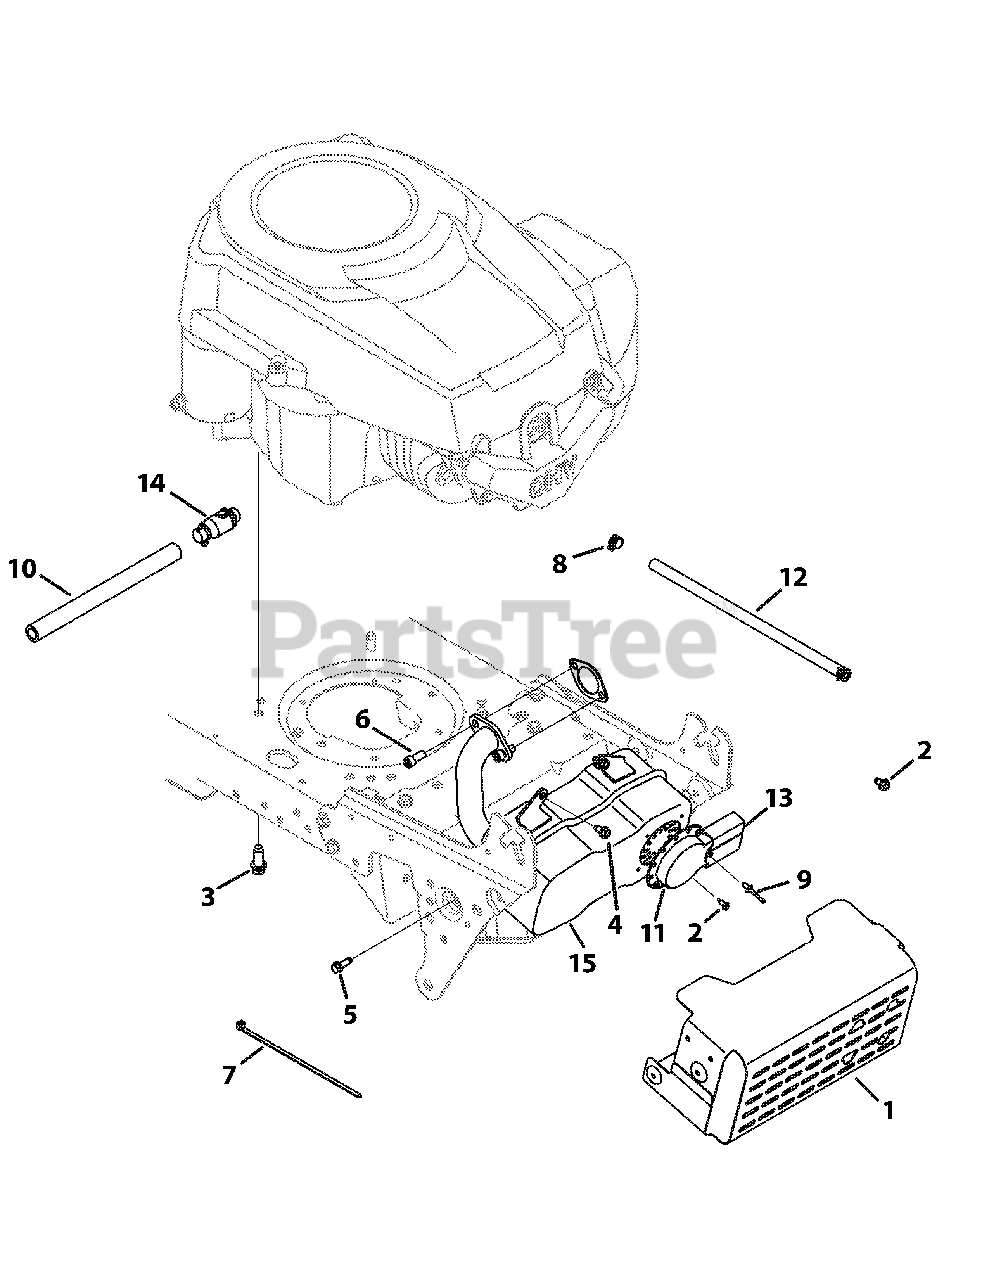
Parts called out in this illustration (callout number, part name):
1	Muffler Shield Assembly with Weld
2	Screw, 8-18 x .500
3	Screw, 3/8-16 x 1.0
4	Screw, 1/4-20 x .500
5	Screw, 1/4-20 x .750
6	Socket Screw, 5/16-18 x .750
7	Cable Tie
8	Clamp Hose, .490 diameter
9	Rivet, .188 x .300
10	Oil Drain, Extension Hose
11	Muffler Deflector
12	Fuel Hose, Low Permeation
13	Muffler Deflector Long
15	Muffler
